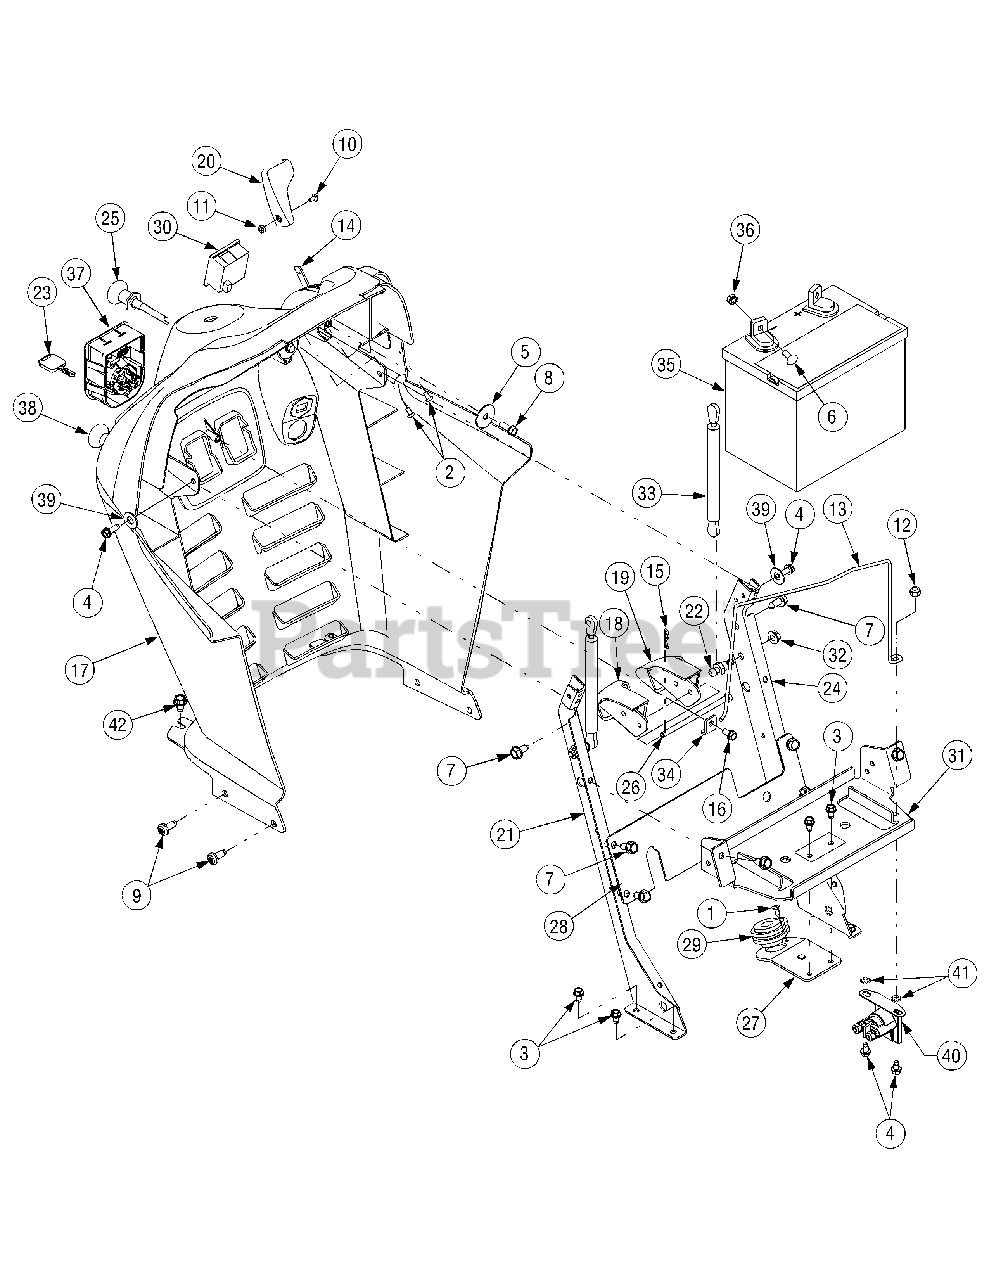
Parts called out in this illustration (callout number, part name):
1	Screw, #10-18 x.5
2	Screw, #10-24 x.375
3	Screw, Self-tapping, 1/4-20, 0.500
4	Screw, Hex. 1/4-20 x.75
5	Flat Washer,.330 x 1.25 x.06
6	Screw, Hex Flange, 1/4-20,.75,
7	Screw, Hex, 5/16-12 x.75
8	Screw, 1/4-15, 0.750
9	Screw, Torx Hd. Tapp. 5/16-18 x.75
10	Screw, Machine, #8-32, 0.375, Trus Phillips
11	Nut, 8-32
12	Nut, Nylon Lock, 1/4-20
14	Control, Throttle, 38.0
15	Internal Cotter Pin,.072 x 1.13
16	Screw, 1/4-15 x.50
17	Dash
18	Lever, Dash, Cruise
19	Lever, Dash, Brake
20	Knob, Throttle Control
23	Ignition Key, Plastic
26	Rod,.250 Dia x 4.25
30	Monitor, Systems Indicator / Hour Meter
33	Gas Spring Cylinder, 3.62 Stroke
35	Battery, 235 CCA
36	Nut, Sems, 1/4-20
37	Switch Module, Ignition
38	Switch, PTO, Yellow
39	Flat Washer,.28 x.74 x.063
40	Solenoid, 12V, 100 Amp
41	Washer, External Lock, 1/4
42	Screw, Hex, 5/16-12 x .50
